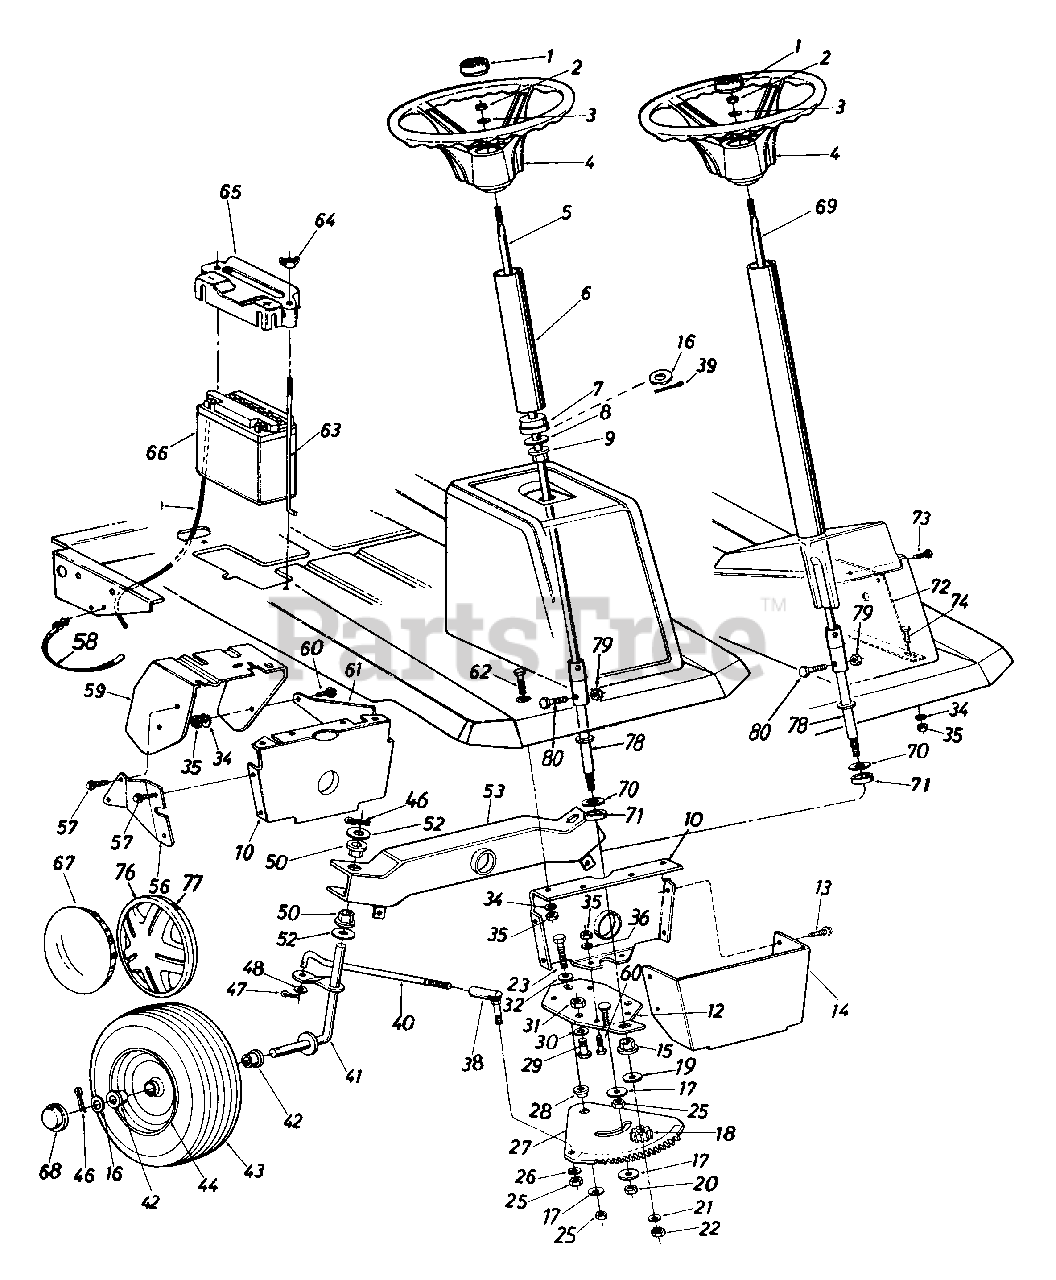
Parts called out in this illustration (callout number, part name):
1	Steering Wheel Cap
2	Hex L-Nut 5/16 - 24 Thd.
3	Bell-Wash. .345" I.D. x .88" O.D.
4	Steering Wheel Ass'y. (3 Spoke)
5	Steering Shaft Ass'y.
8	FL-Wash. .635" I.D. x 1.24" O.D.
9	Hex Flange Bearing
13	Hex Wash. Hd. AB-Tap Scr. 1/4 x .62" Lg.
16	FL-Wash. .640" I.D. x 1.5" O.D.
17	FL-Washer 3/8" I.D. x 1.37" O.D.
18	Steering Pinion Gear
19	FL-Wash. .510" I.D. x 1" O.D.
20	Hex L-Nut 3/8 - 24
21	FL-Wash. .34" I.D. x .68" O.D.
22	Hex Nut 5/16 - 24 Thd.
23	Hex Bolt 3/8 - 24 x 1.5" Lg. (Grade 5)
25	Hex Nut 3/8-24 Thd.
26	L-Wash. 3/8" I.D.
27	Steering Gear Segment
28	Shoulder Spacer .622" Dia. x .218
29	Hex Bolt (Nylon) 1/2 - 13 x .75"
30	FL-Wash. .530" I.D. x .930"
31	Hex Nut 1/2 - 13 Thd.
32	Bell-Wash. .385" I.D. x .88"
34	L-Wash. 5/16" I.D.
35	Hex Nut 5/16 - 18 Thd.
36	Spr. Wash. .32" I.D. x .62" O.D.
38	Ball Joint Ass'y. 3/8 - 24 Thd.
39	Cotter Pin 1/8" Dia. x 1.00" Lg
40	Steering Tie Rod
41	Front Axle Ass'y. - R.H.
42	Flange Bearing 11 X 4.0 Nylon Brg.
46	Cotter Pin 1/8" Dia. x 1.25"
47	Cotter Pin 1/8" Dia. x 1.00"
48	FL-Wash. .385" I.D. x .87"
50	Hex Flange Bearing
52	FL-Wash. .635" I.D. x 1.12"
53	Pivot Bar Ass'y.
58	Cable Tie
59	Clutch-Brake Pedal Ass'y.
60	Hex Bolt 5/16 - 18 x .75" Lg.
63	Battery Hold Down Rod
64	Wing Nut Solid 1/4 - 20 Thd.
65	Battery Hold Down Cover
66	12V Battery
67	Chrome Hub Cap
68	Plastic Hub Cap
69	Steering Shaft Ass'y.
70	FL-Wash. .635" I.D. x 1.24" O.D.
71	Spacer (Plastic)
74	Hex Bolt 5/16 - 18 x 2.00" Lg.
76	Hub Cap - Beige
77	Spring Clip
78	Steering End Adapter
79	Hex Nylon L-Nut 1/4 - 20 Thd.
80	Hex Bolt 1/4 - 20 x 1.31" Lg.
